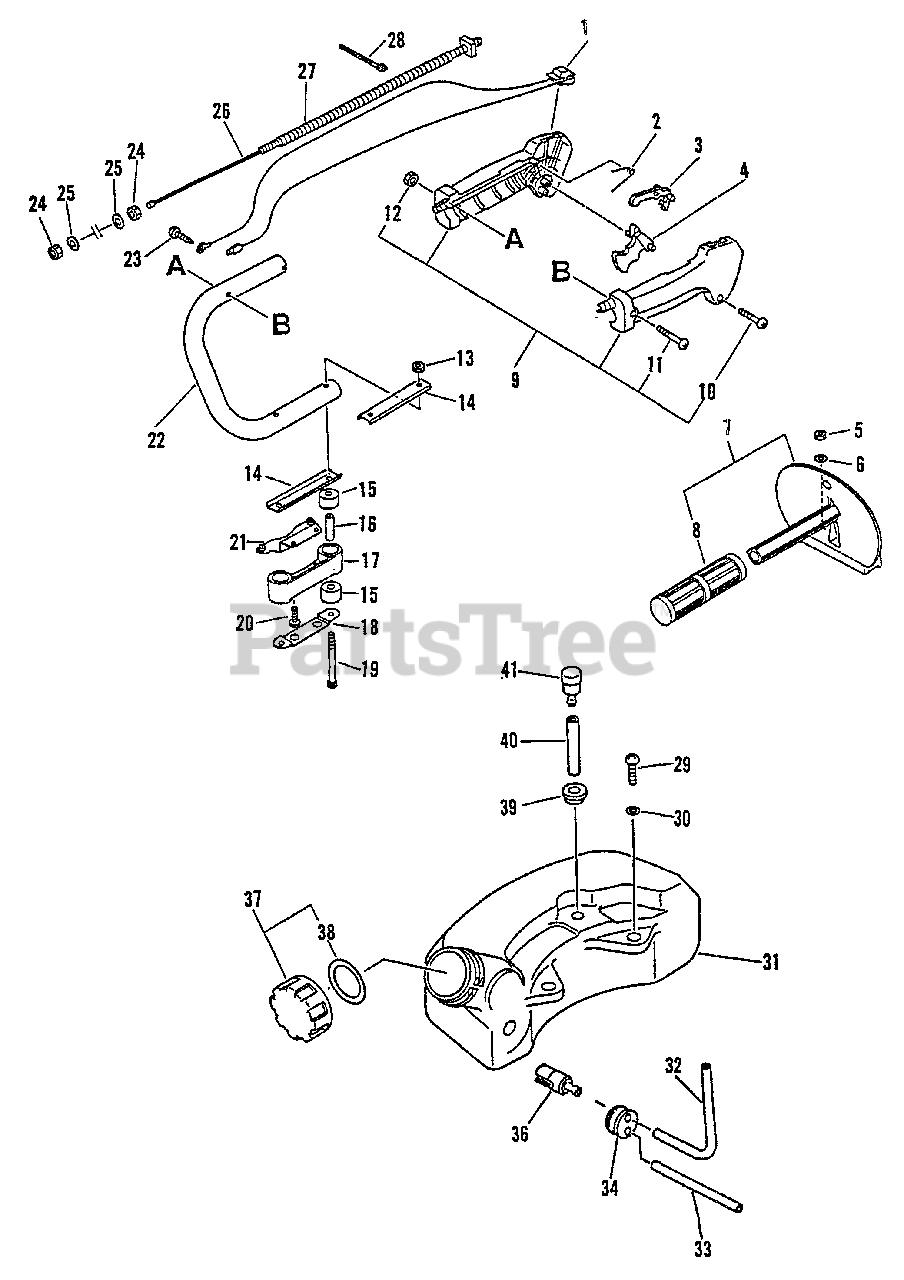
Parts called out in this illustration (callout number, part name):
1	IGNITION SWITCH ASSY
2	SPRING, LOCKOUT LEVER
3	LOCKOUT, THROTTLE
4	TRIGGER, THROTTLE
6	WASHER - 6
7	HANDLE ASSY - FRONT
8	GRIP, HANDLE
9	THROTTLE CONTROL ASSY
10	SCREW - 3X25
11	SCREW - 5X30
13	LOCKNUT - 5
14	BRACKET, HANDLE - LOWER
16	SPACER
17	BRACKET, HANDLE
18	PLATE, CUSHION
19	SCREW - 5X60
20	SCREW - 5X16
22	HANDLE - REAR
23	SCREW - 5X10
25	WASHER - 6
26	CABLE, THROTTLE
28	TIE, CABLE
29	SCREW - 5X16
30	WASHER - 5
31	TANK, FUEL
32	PIPE, FUEL - CORRUGATED
33	PIPE - 3X6X110 -- CLEAR
34	GROMMET
36	FILTER, FUEL
37	CAP ASSY
38	GASKET, CAP
39	GROMMET
40	PIPE - 3X6X35 -- BLACK
41	VENT, FUEL TANK
